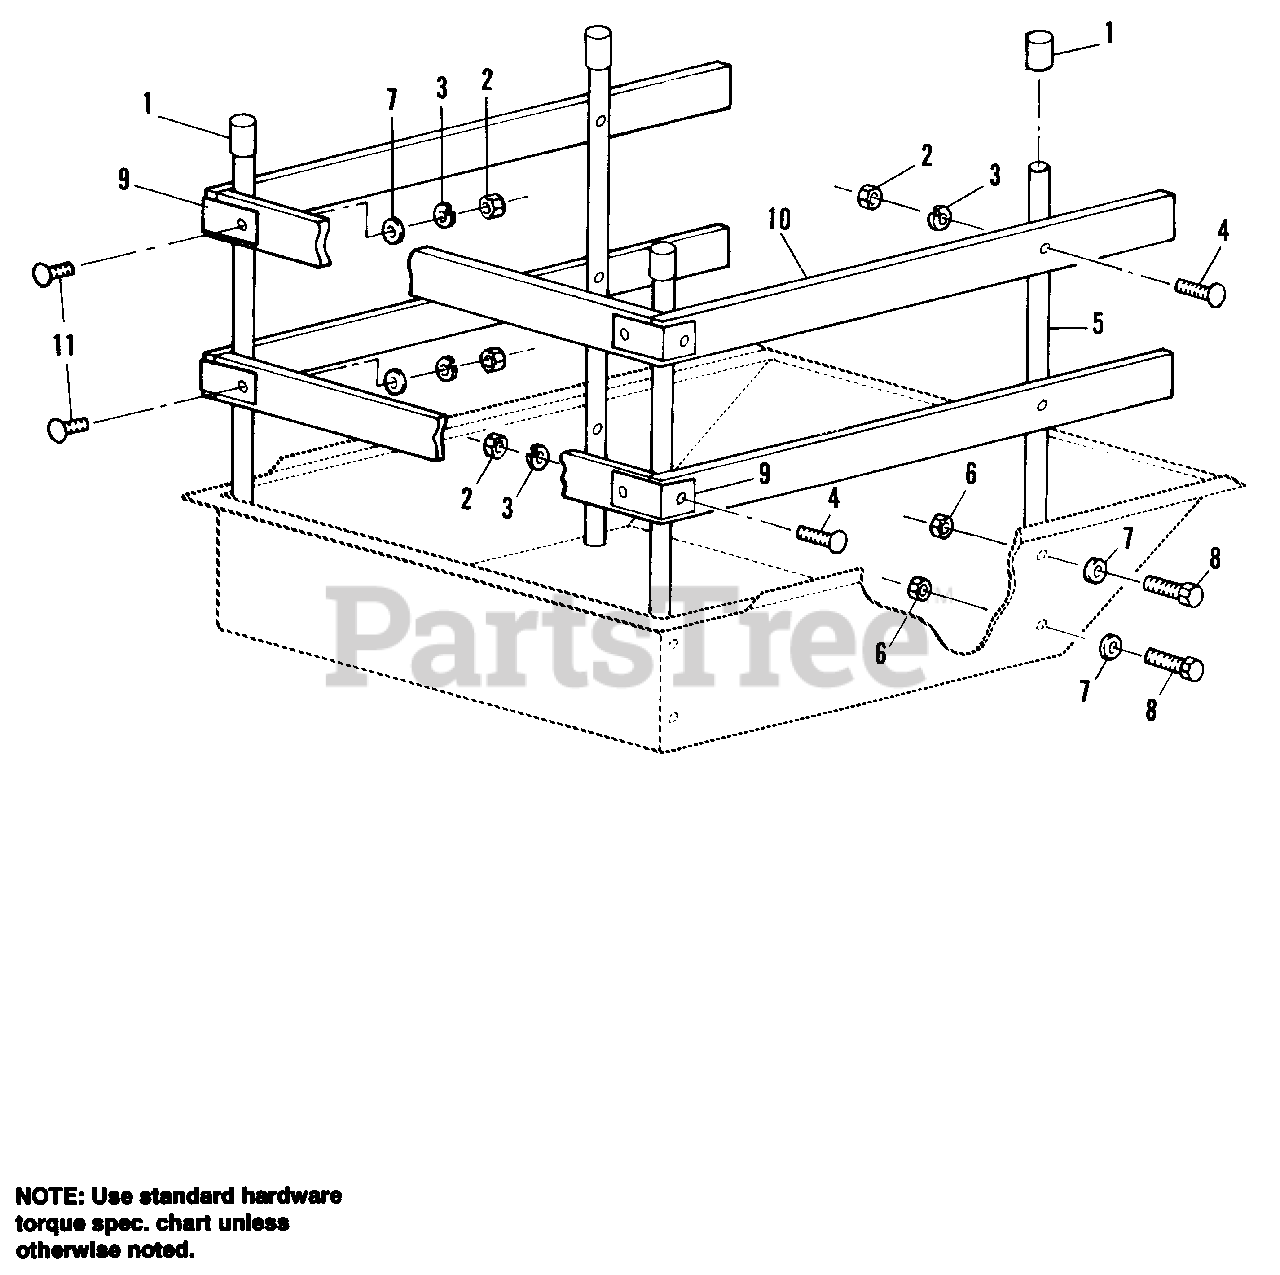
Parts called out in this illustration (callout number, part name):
1	CAP, Plastic
2	NUT, Hex, 5/16-18
3	LOCKWASHER, 5/16
4	BOLT, Carriage, 5/16-18 x 2
6	NUT, Loc, 5/16-18
7	WASHER, 5/16
8	CAPSCREW, Hex, 5/16-18 x 1-1/2
10	SIDE, Wood (Drill holes and cut to size.)
11	BOLT, Carriage, 5/16-18 x 1-1/4
